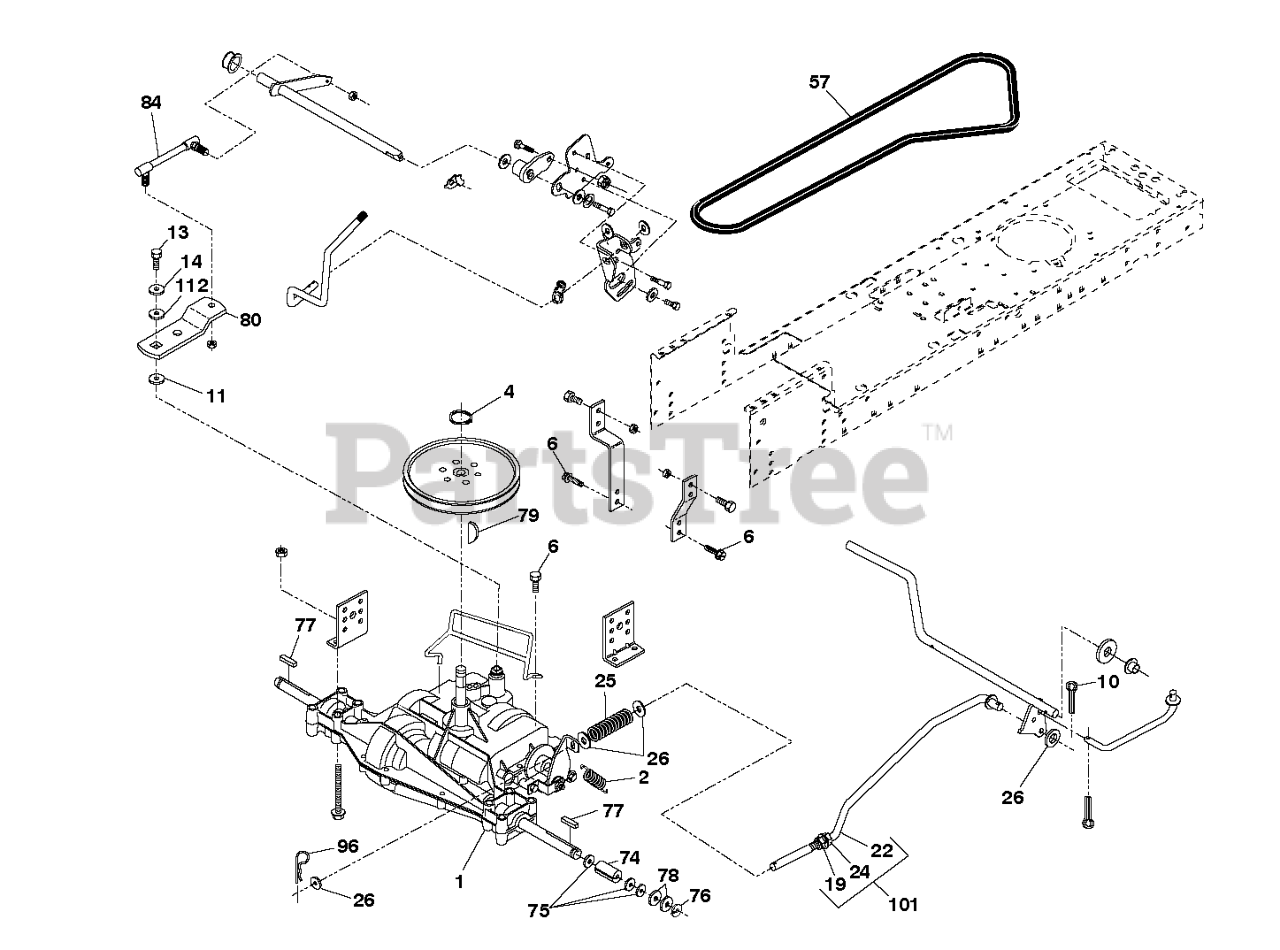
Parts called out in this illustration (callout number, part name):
2	SPRING,BRAKE RETURN
4	RETAINING RING LT
6	SCREW 5/16"
10	PIN COTTER
11	WASH-SHFT PLT LT
13	BOLT 1/4-28X3/4
14	LOCKWASHER
19	NUT
24	NUT
25	SPRING ROD LT
26	WASHER
57	BELT, V GROUND DRIVE 95 25
74	SPACER AXLE
77	SQUARE KEY
79	KEY STD (1373) DANA
84	LINK.TRNSAXLE
96	RETAINER M
101	ROD ASM.BRK.PMST.LT/STL.18/20"
112	LOCKWASHER
